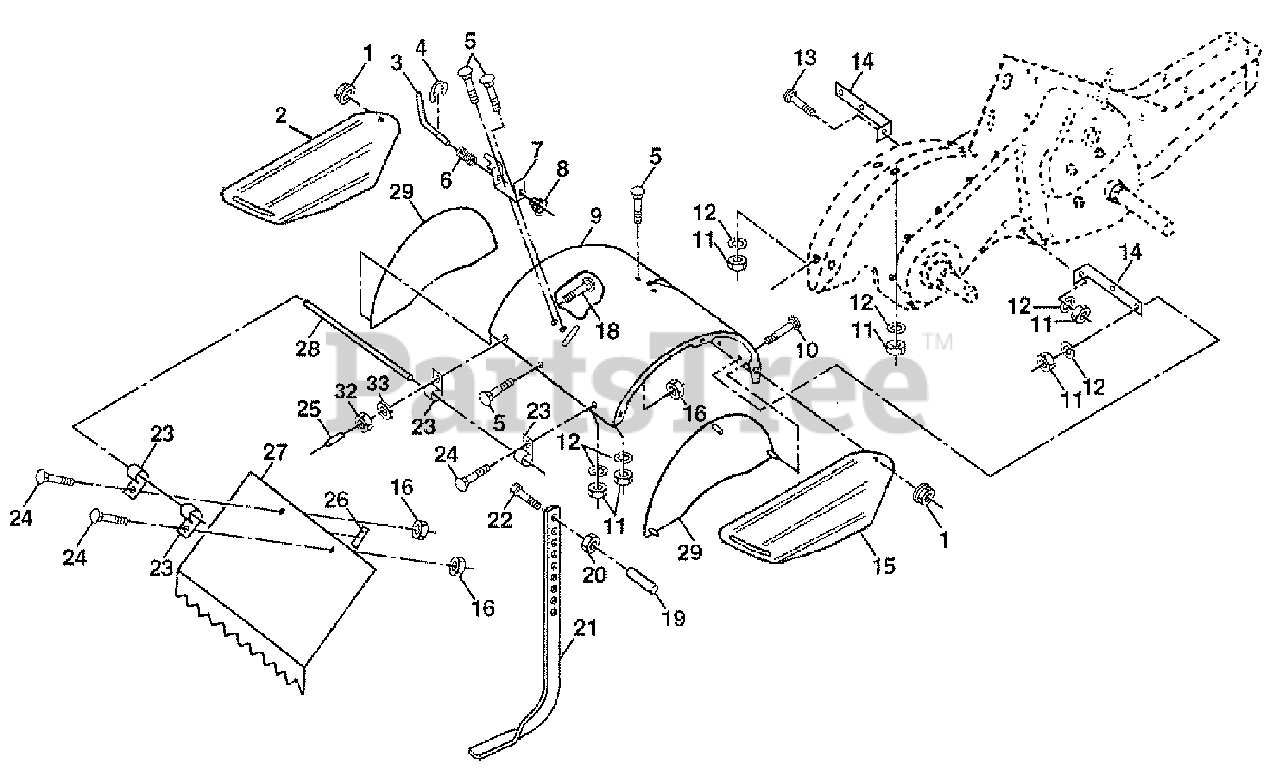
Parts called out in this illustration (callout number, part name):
1	Nut, Flange 5/16-18
2	Shield, Side, Outer L. H.
3	Pin, Stake, Depth
4	Ring, Klip
5	Bolt, Carriage 5/16-18 x 3/4
6	Spring
7	Bracket, Latch
8	Spring, Depth Stake
9	Shield, Tine
10	Bolt 5/16-18 x 1
11	Nut, Hex 5/16-18
12	Washer, Lock 5/16
13	Bolt, Carriage 5/16-18 x 1-1/4
14	Bracket, Shield Tine
15	Shield, Side, Outer R.H.
16	Nut, Hex Flange 1/4-20 UNC
18	Bolt, Carriage 1/4-20 x 1-1/4 Gr. 5
19	Grip
20	Nut, Hex 3/8-16
21	Stake, Depth
22	Bolt, Hex 3/8-16 x 2
23	Hinge
24	Bolt, Carriage 1/4-20 x 1/2 Gr. 5
25	Cap, Vinyl
26	Pad, Idler
27	Shield, Leveling
28	Pin, Hinge
29	Shield, Side
32	Nut Fin Hex 1/4-20 UNC
33	Washer Lock Hvy Helical 1/4
